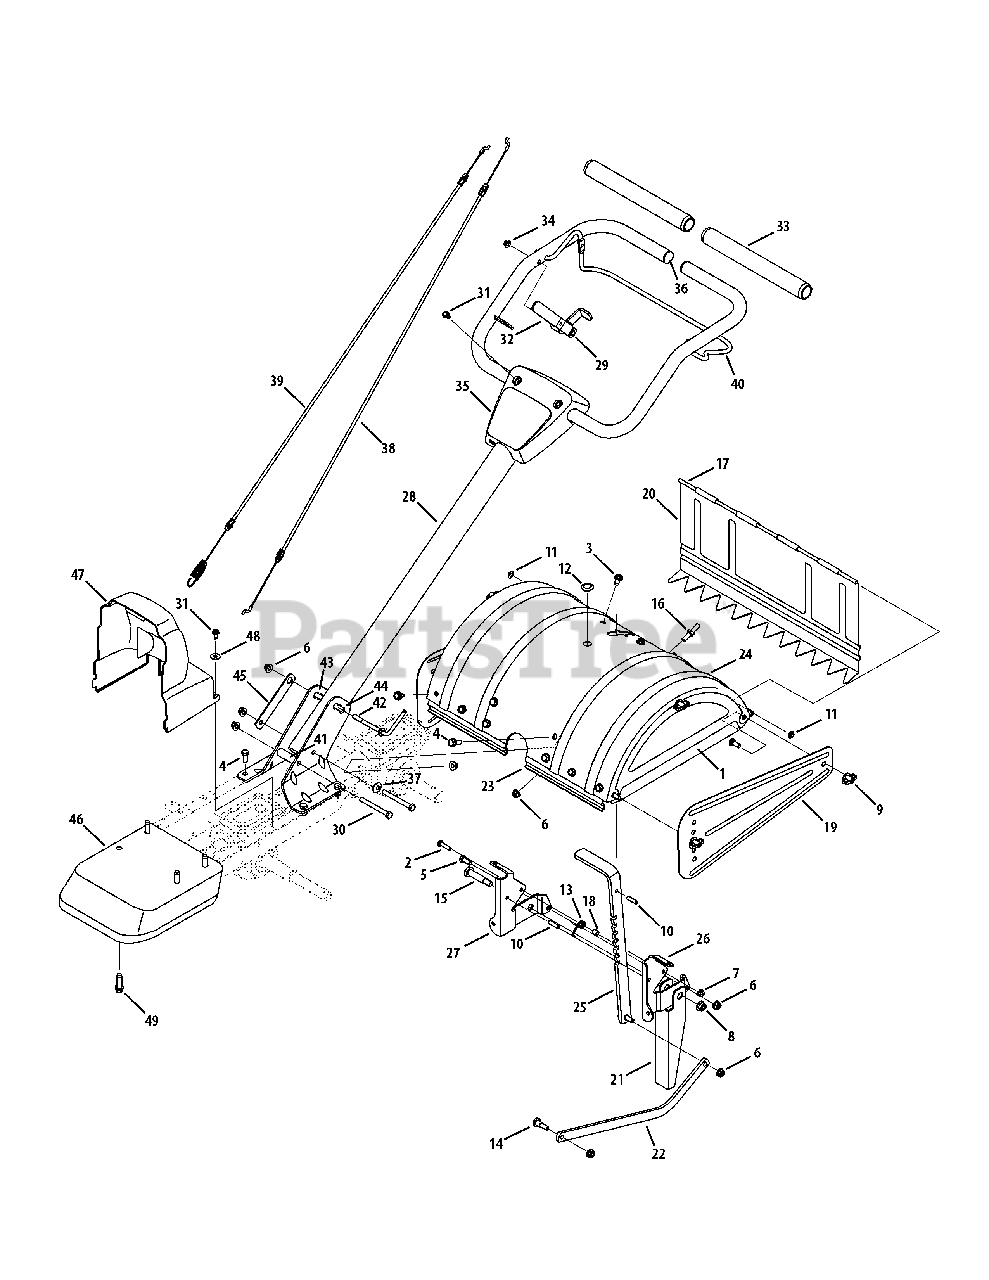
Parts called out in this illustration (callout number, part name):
1	End Cover Assembly
2	Hex Head Screw, 1.4-20 x 1
3	Hex Head Screw, 5.16-18 x .500
4	Hex Head Screw, 5.16-18 x .875
5	Hex Head Screw, 5.16-18 x .75
6	Nylon Hex Lock Nut, 5.16-18
7	Nylon Hex Lock Nut, 1.4-20
8	Flange Lock Nut, 3.8-16
9	Wing Nut, 5.16-18
10	Spirol Pin
11	Cap Nut, 1.4 Rod
12	Hole Plug
13	Torsion Spring
14	Shoulder Screw, .405 x .435 5.16-18
15	Shoulder Screw, .498 x 1.635
16	Stop Screw
17	Tiller Flap Rod
18	Spacer
19	Side Shield
20	Rear Tine Shield
21	Reverse Stop Arm
23	Tine Shield Mounting Bracket
24	Tine Shield
25	Adjustable Depth Bar
26	Tail Bracket, LH
27	Tail Bracket, RH
28	Upper Handle Assembly
29	Reverse Handle Assembly
30	Hex Head Screw, 5/16-18 x 3.00
31	Self-Tapping Screw, 1/4-20 x 1/2
32	Reverse Handle Grip
33	Foam Handle Grip
34	Cap Nut, .3125 dia.
35	Handle Cover
36	Plug End
37	Bell Washer, .340 x .872 x .060
38	Reverse Cable
39	Forward Cable
40	Clutch Bail
41	Spacer, .322 x .625 x 2.00
42	Handle Crank
43	Handle Bracket, RH
44	Handle Bracket, LH
45	Retainer Nut Bracket
46	Front Bumper
47	Belt Cover
48	Flat Washer, .28 x .74 x .063
49	SEMS Screw, 3/8-16
